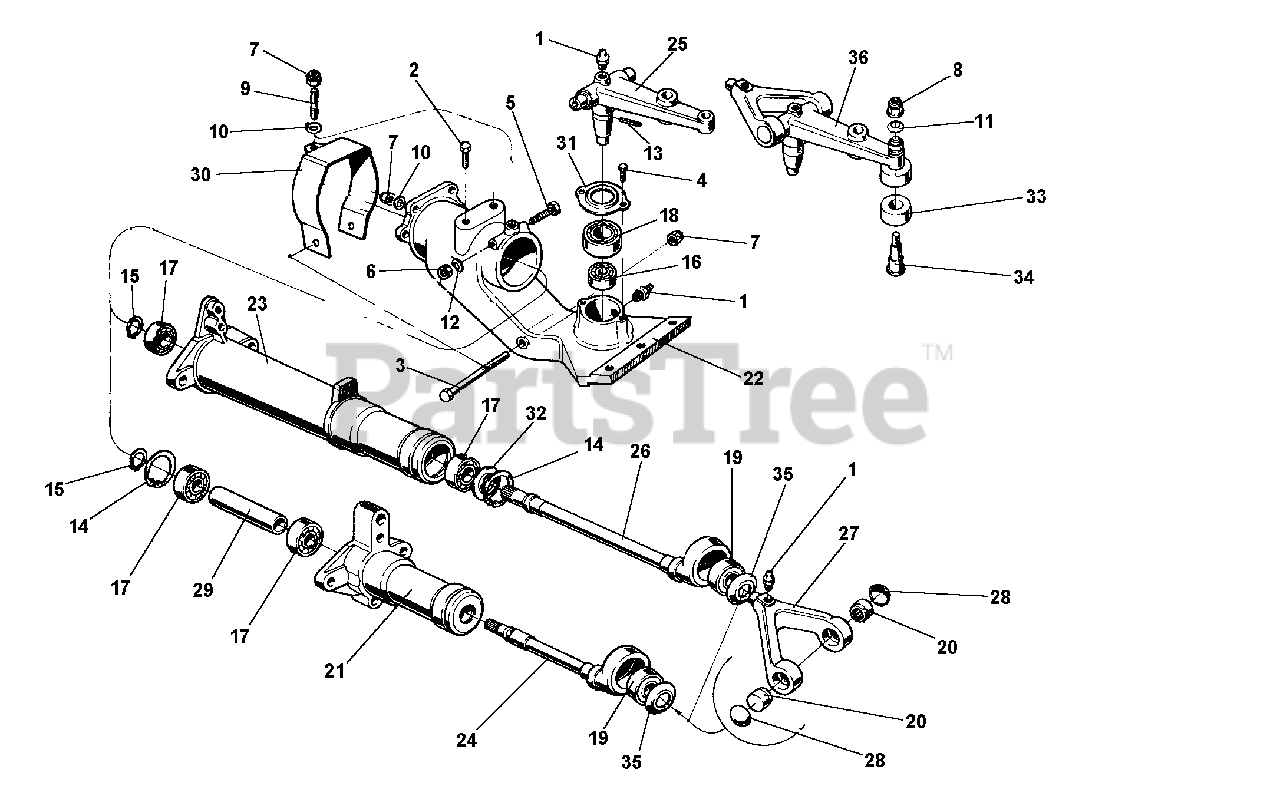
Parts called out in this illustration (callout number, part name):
1	GREASE ZIRT M10
2	SCREW TE M8 X 12
3	SCREW TE M8 X 100
4	SCREW TE M6 X 16
5	SCREW TE M6 X 70
6	NUT, SELF LOCKING M6
7	NUT, SELF LOCKING M8
8	NUT, SELF LOCKING
10	WASHER, FLAT 8.4
11	SUPER WASHER 10
12	LOCK WASHER 6.4
13	PIN, LOCKING 4 X 35
14	CIRCLIP, INTERNAL D 47
15	CIRCLIP, EXTERNAL D 20
16	BEARING 15 XZ 35 X 11 6202
17	BEARING 20 X 47 X 14 6204 2RS
20	BUSHING PIT VIO 44855000
21	BUSHING WITH FLANGE
22	BAR SUPPORT
23	SHAFT HOUSING
24	ECCENTRIC SHAFT
25	BLADE CRANK
26	LONG ECCENTRIC SHAFT
30	ECCENTRIC PROTECTION
31	COVER, BEARING
33	BLADE BUSHING
36	CRANK WITH FORK
